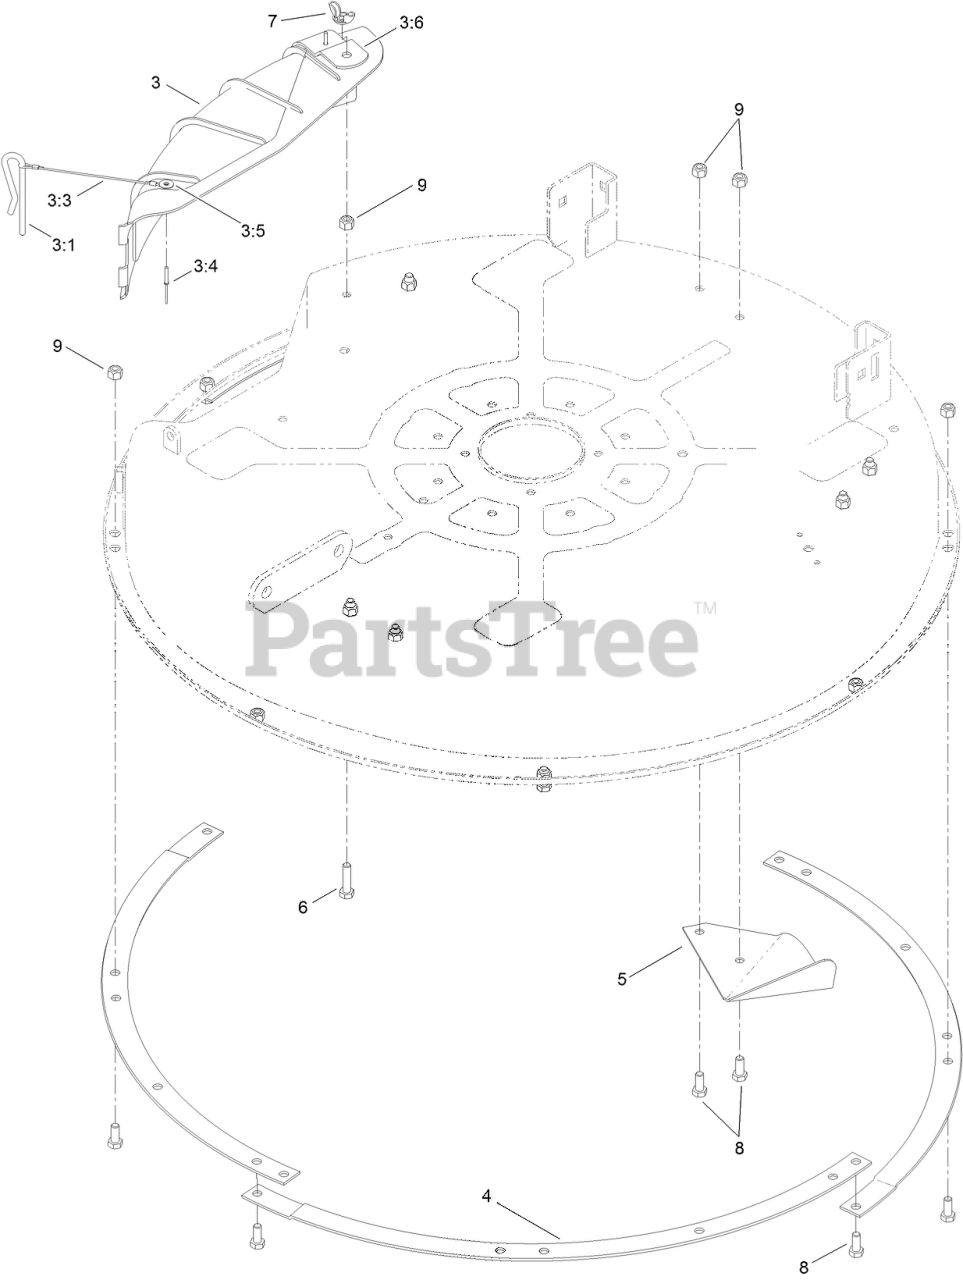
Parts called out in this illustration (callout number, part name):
3	DISCHARGE COVER ASM
3:1	PIN-LOCKING, CHUTE
3:3	LANYARD
3:4	RIVET-BLIND
3:5	WASHER-PLAIN
4	RING-DECK
6	SCREW-HH
7	NUT-WING
8	SCREW-HH
9	NUT-LOCK, NI
